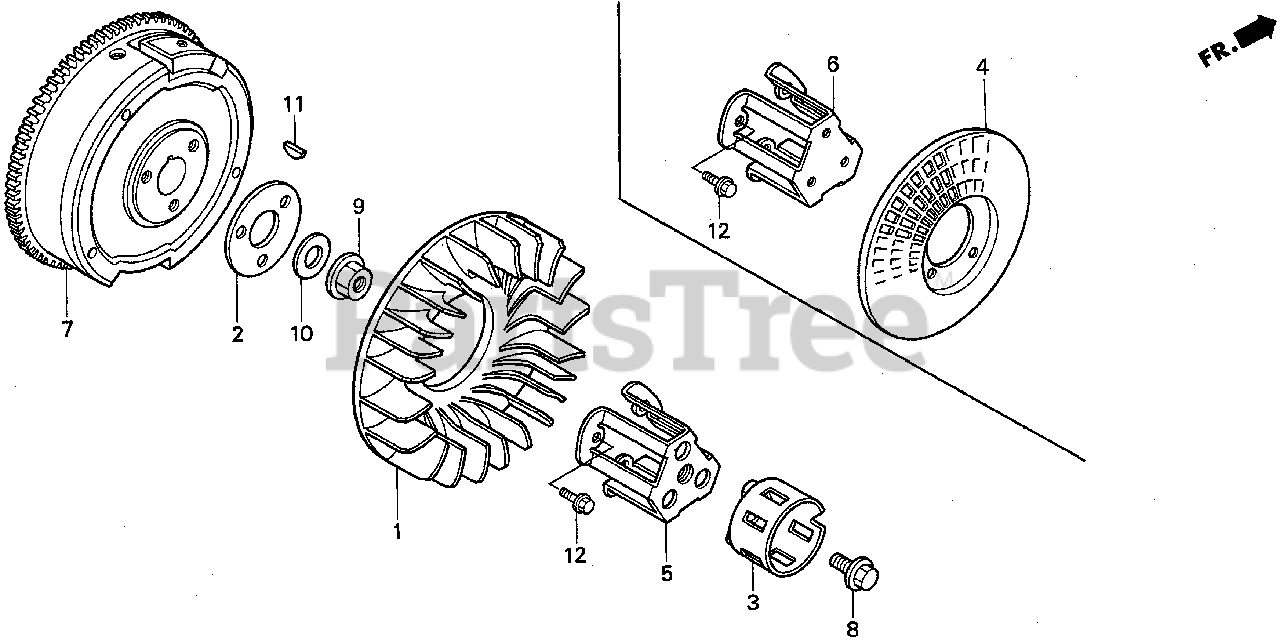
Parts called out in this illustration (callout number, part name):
1	FAN, COOLING
2	PLATE, COOLING FAN SETTING
4	GRID, SCREEN (P.T.O.)
6	HOLDER, SCREEN GRID
7	FLYWHEEL
9	NUT, FLANGE (20MM)
10	WASHER (20MM)
11	KEY, SPECIAL WOODRUFF (25X18)
12	BOLT, FLANGE (8X16)
